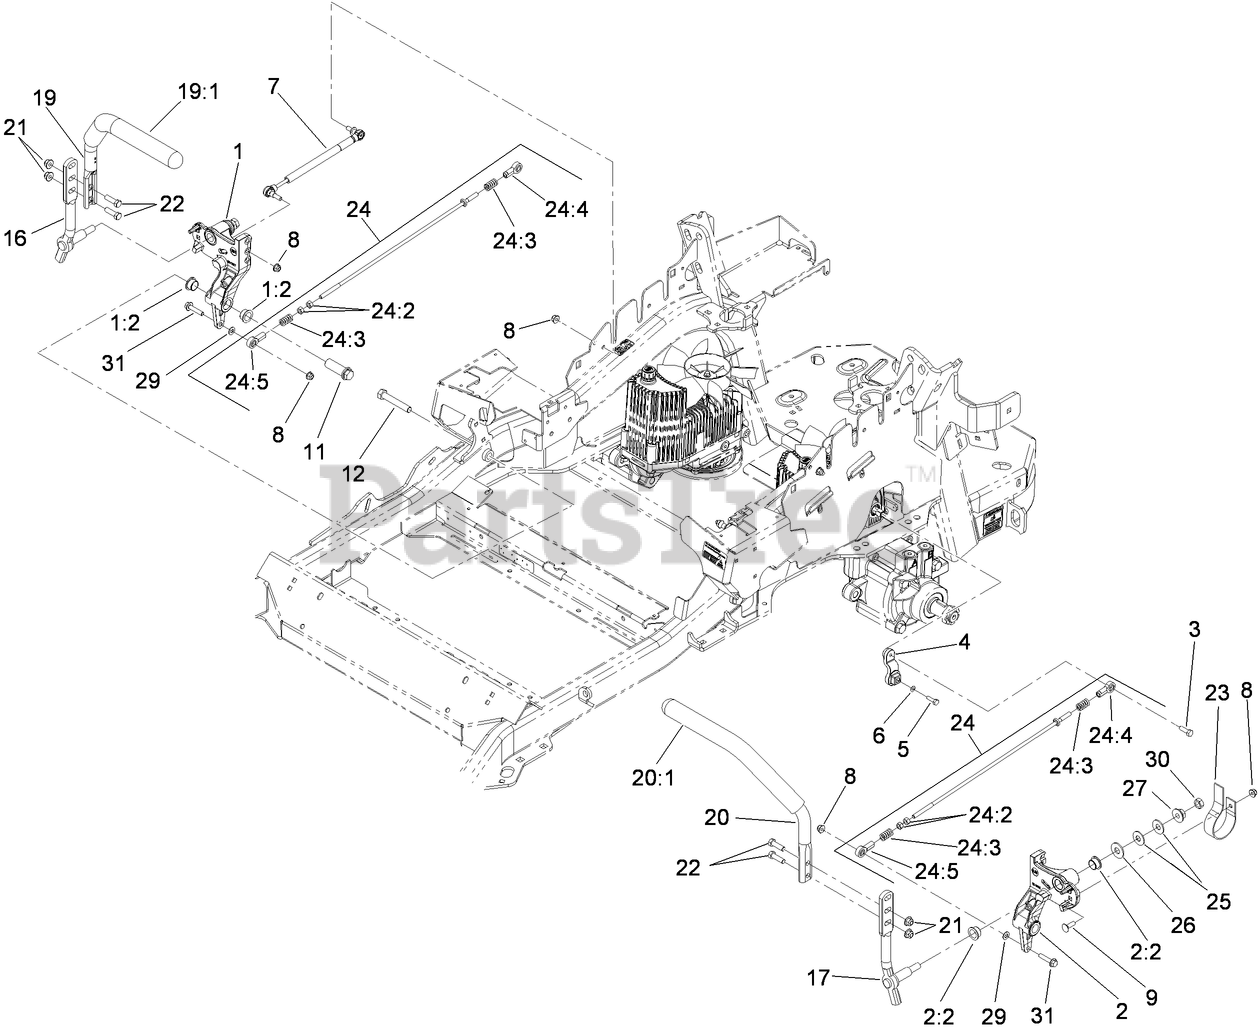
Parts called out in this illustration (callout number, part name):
1	RH MOTION CONTROL AND BUSHING ASM
1:2	BUSHING-FLANGE
2	LH MOTION CONTROL AND BUSHING ASM
2:2	BUSHING-FLANGE
3	SCREW-HH, THREAD LOCKING
4	ARM-CONTROL, PUMP
5	SCREW-HH
6	WASHER-SPRING
7	DAMPER-CONTROL, MOTION
8	NUT-HF, NI
9	BOLT-CARR
11	HUB-THREADED
12	SCREW-HH
16	LEVER-CONTROL MOTION, RH
17	LEVER-CONTROL MOTION, LH
19	RH STEERING HANDLE ASM
19:1	Grip-Control, Motion
20	LH STEERING HANDLE ASM
20:1	Grip-Control, Motion
21	NUT-HF, NI
22	SCREW-HH
23	SPRING-LEAF
24	FRONT PUMP LINKAGE ASM
24:2	NUT-HEX
24:3	SPRING-COMPRESSION
24:4	BALLJOINT-LH
24:5	BALLJOINT-RH
25	WASHER-SPRING
26	WASHER-FLAT
27	NUT-HF
29	WASHER-PLAIN
30	NUT-JAM
31	SCREW-HHF
